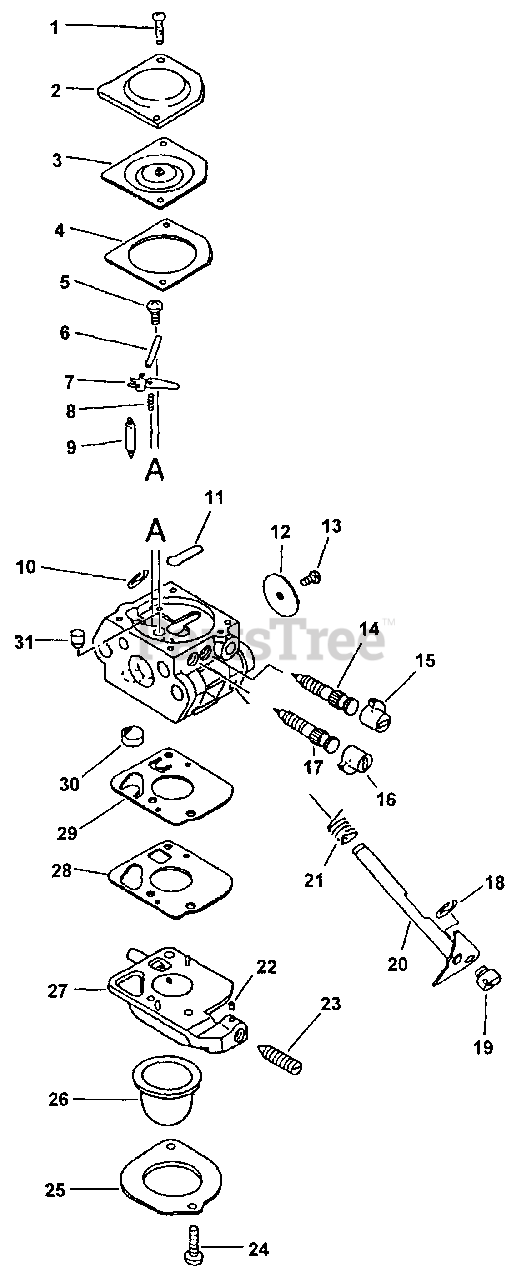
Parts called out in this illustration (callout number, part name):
2	COVER, METERING DIAPHRAGM
3	DIAPHRAGM, METERING
4	GASKET, METERING
6	PIN, METERING LEVER
7	LEVER, METERING
8	SPRING, METERING LEVER
9	VALVE, NEEDLE
11	PLUG, WELCH
12	VALVE, THROTTLE
14	NEEDLE, LOW SPEED
15	CAP, LIMITER - WHITE
16	CAP, LIMITER - RED
17	NEEDLE, HIGH SPEED
20	SHAFT, THROTTLE
21	SPRING, THROTTLE RETURN
22	PIECE, FRICTION
23	SCREW, IDLE ADJUST
25	RETAINER
26	BULB, PURGE
27	BODY ASSY, PURGE
30	STRAINER
31	NOZZLE, CHECK VALVE
